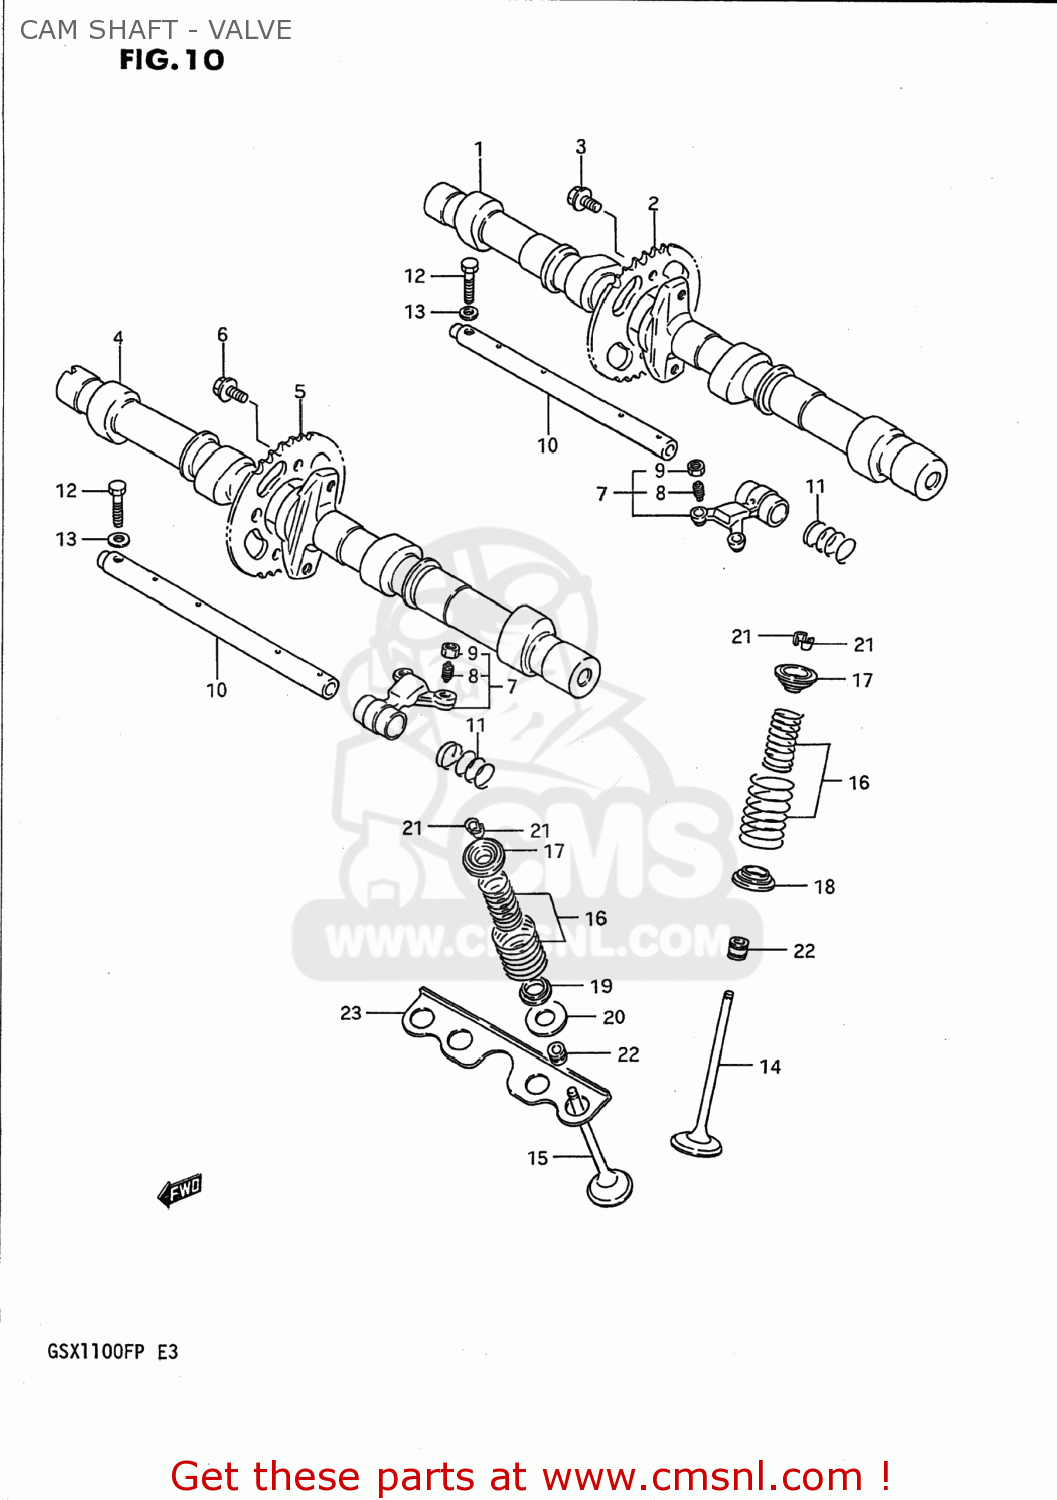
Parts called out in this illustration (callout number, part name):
1	CAMSHAFT
2	SPROCKET,CAMSHAFT
3	BOLT(7X11)
4	CAMSHAFT,EXHAUST
5	SPROCKET,CAMSHAFT
6	BOLT(7X11)
7	ARM,VALVE ROCKER
8	SCREW,TAPPET ADJUSTING
9	NUT,ADJUSTING
10	SHAFT,VALVE ROCKER ARM
11	SPRING
12	BOLT
13	WASHER, LOWER
14	VALVE,INTAKE
15	VALVE,EXHAUST
16	SPRING SET,VALVE
17	RETAINER,VALVE SPRING
18	SEAT,VALVE SPRING
19	SEAT,VALVE SPRING
20	SEAT,VALVE SPRING EXH OUTER
21	COTTER VALVE
22	SEAL,OIL(5X10X9.7)
23	PLATE
